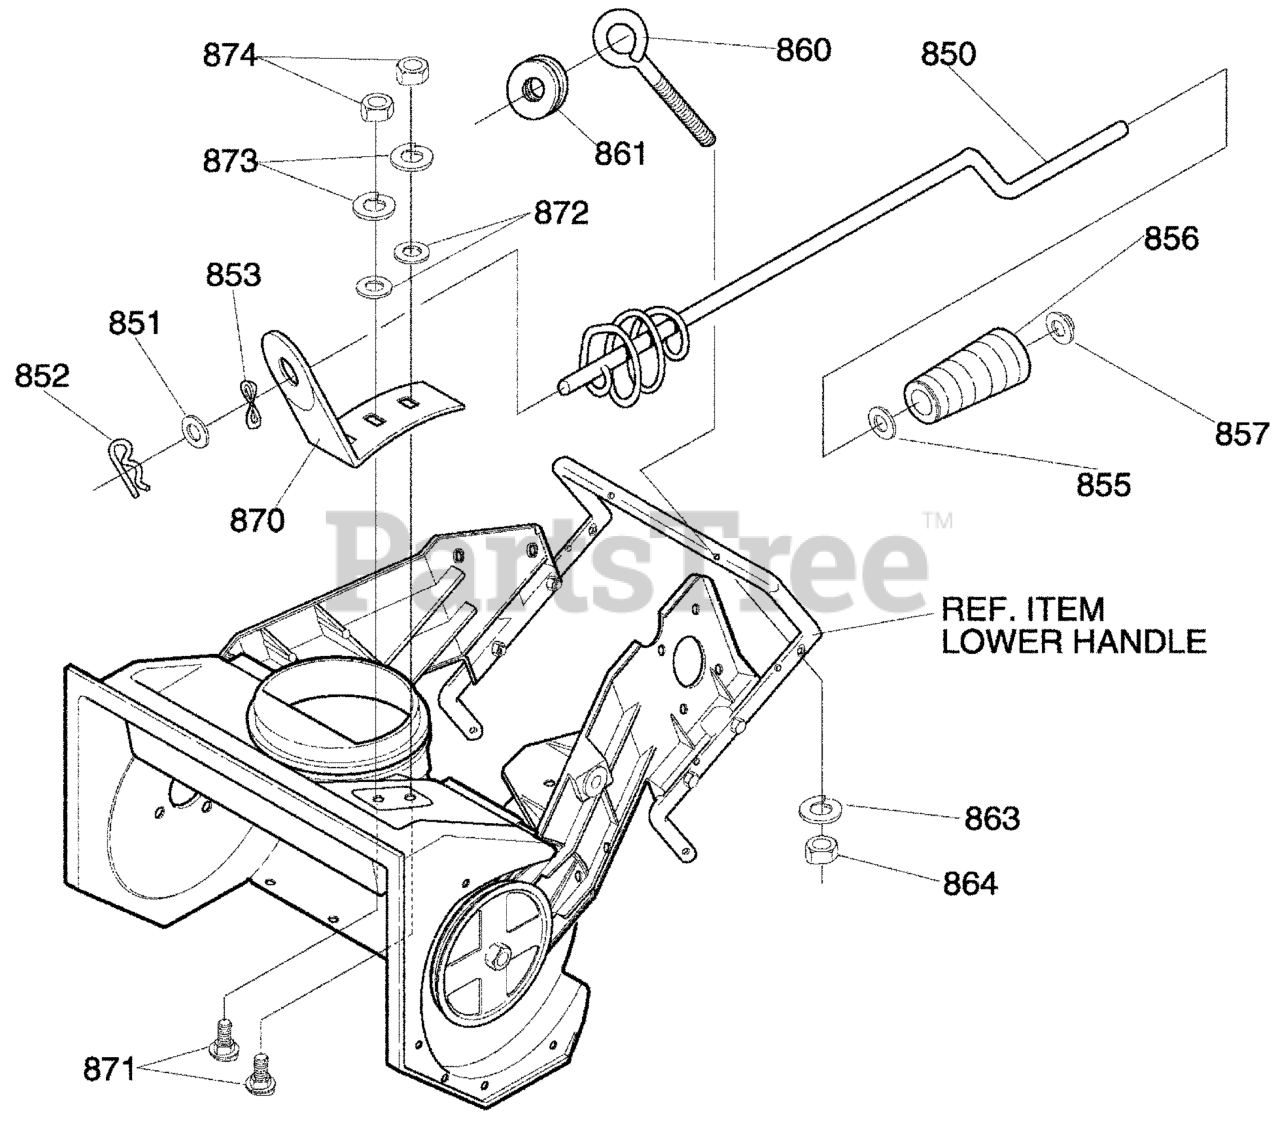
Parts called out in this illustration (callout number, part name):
850	ROD, ASSY UPPER CHUTE CONTROL
851	WASHER, FLAT .406X.81X.066
852	PIN, COTTER
853	WASHER, CURVED SPRING
855	WASHER, FLAT .406X.81X.066
856	KNOB, SLEEVE
857	NUT, PUSH
860	BOLT, EYE 3/8-16X2.00
861	GROMMET, EYE BOLT
863	WASHER
864	NUT, HEX JAM 3/8-16
870	BRACKET, CHUTE ROTATE
871	BOLT, CARRIAGE 5/16-18X.75
872	WASHER, FLAT .349X.69X.066
873	WASHER .328X.60X.09
874	NUT, HEX 5/16-18
